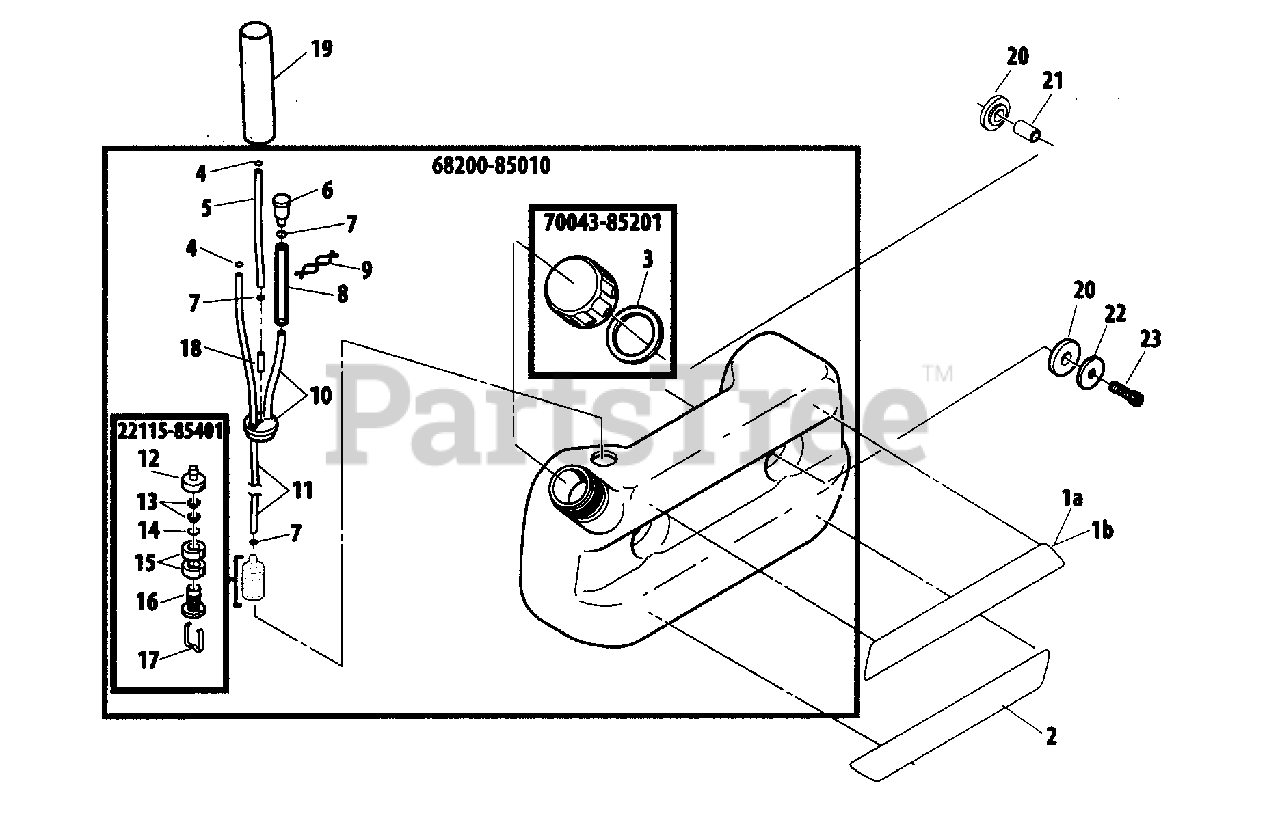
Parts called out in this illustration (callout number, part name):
1A	NAME LABEL (EB480)
1B	NAME LABEL (EB500)
2	LABEL
3	GASKET, FUEL CAP
4	CLIP
5	PIPE, FUEL RETURN
6	VENT ASSY
7	CLIP Ø6
8	TUBE, INSULATOR
9	CLIP
10	GROMMET, FUEL W/VENT PIPE
11	TUBE
12	WEIGHT, FUEL LINE
13	SCREEN, FILTER
14	RING, RETAINING
15	FILTER, FUEL
16	BODY, FUEL FILTER
17	CLIP, FILTER
18	CONNECTOR, PIPE
19	TUBE, INSULATOR
20	CUSHION
21	BUSHING
22	COLLAR Ø23ר6.5×L3.2
23	BOLT M6×25
22115-85401	FILTER, FUEL
68200-85010	FUEL TANK ASSY
70043-85201	CAP ASSY, FUEL
